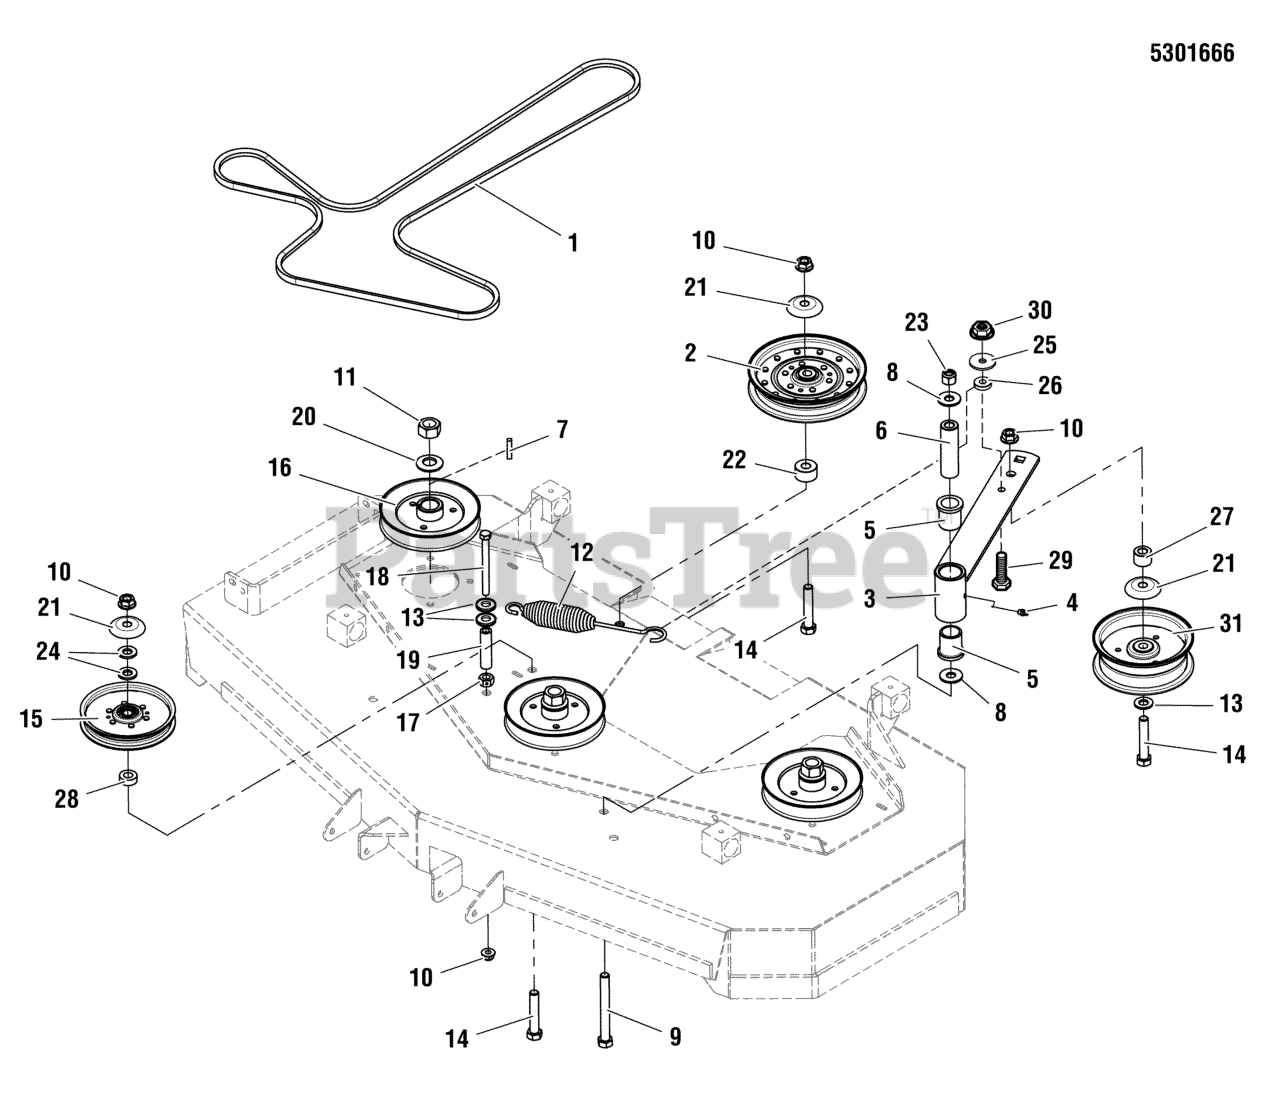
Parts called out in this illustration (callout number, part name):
1	BELT,# 7-5335
3	WELD, IDLER ARM - RED
4	GREASE FITTING, 1/4-28 STRAIGHT
5	BUSHING, FLANGE
6	SPACER, .52 X 1.00 X 3.42
7	KEY, 1/4 SQ. X 1-1/4
8	WASHER, 1/2 USS
9	BOLT, 1/2-13 X 4-1/2 GD5
10	NUT, Hex Flange, Nylock, 1/2-13
11	NUT, 3/4-16 HEX
12	SPRING, EXTENSION, SWIVEL
13	WASHER, 1/2 SAE
14	BOLT, 1/2-13 X 2-3/4 GD5 CZ
15	PULLEY, FLAT IDLER, 5.0 X .75
16	PULLEY, 5.540OB X .985ID, SINGLE B-SEC
17	NUT, 1/2-13 HEX
18	BOLT, 1/2-13 X 4" GD5 CZ
19	HOSE, 1/2" PUSH-ON 2.25"
20	WASHER, 3/4 BELLEVILLE
21	SHIELD, PULLEY BEARING
22	SPACER, .52 X 1.25 X .70
23	NUT, 1/2-13 HEX NYLON LOCK
24	WASHER, 1/2 GD9 YZ
25	WASHER, .390 X 1.50 X .109 YZ
26	SPACER, .39 X 1.00 X .25
27	SPACER, .52 X 1.00 X .75
28	SPACER, .52 X 1.00 X .38
29	BOLT, 3/8-16 X 1-1/4" GD5 CZ
30	NUT, 3/8-16 HEX NYLOCK FLANGE
31	PULLEY, IDLER, 5.00 WIDE W/ .51 BC
